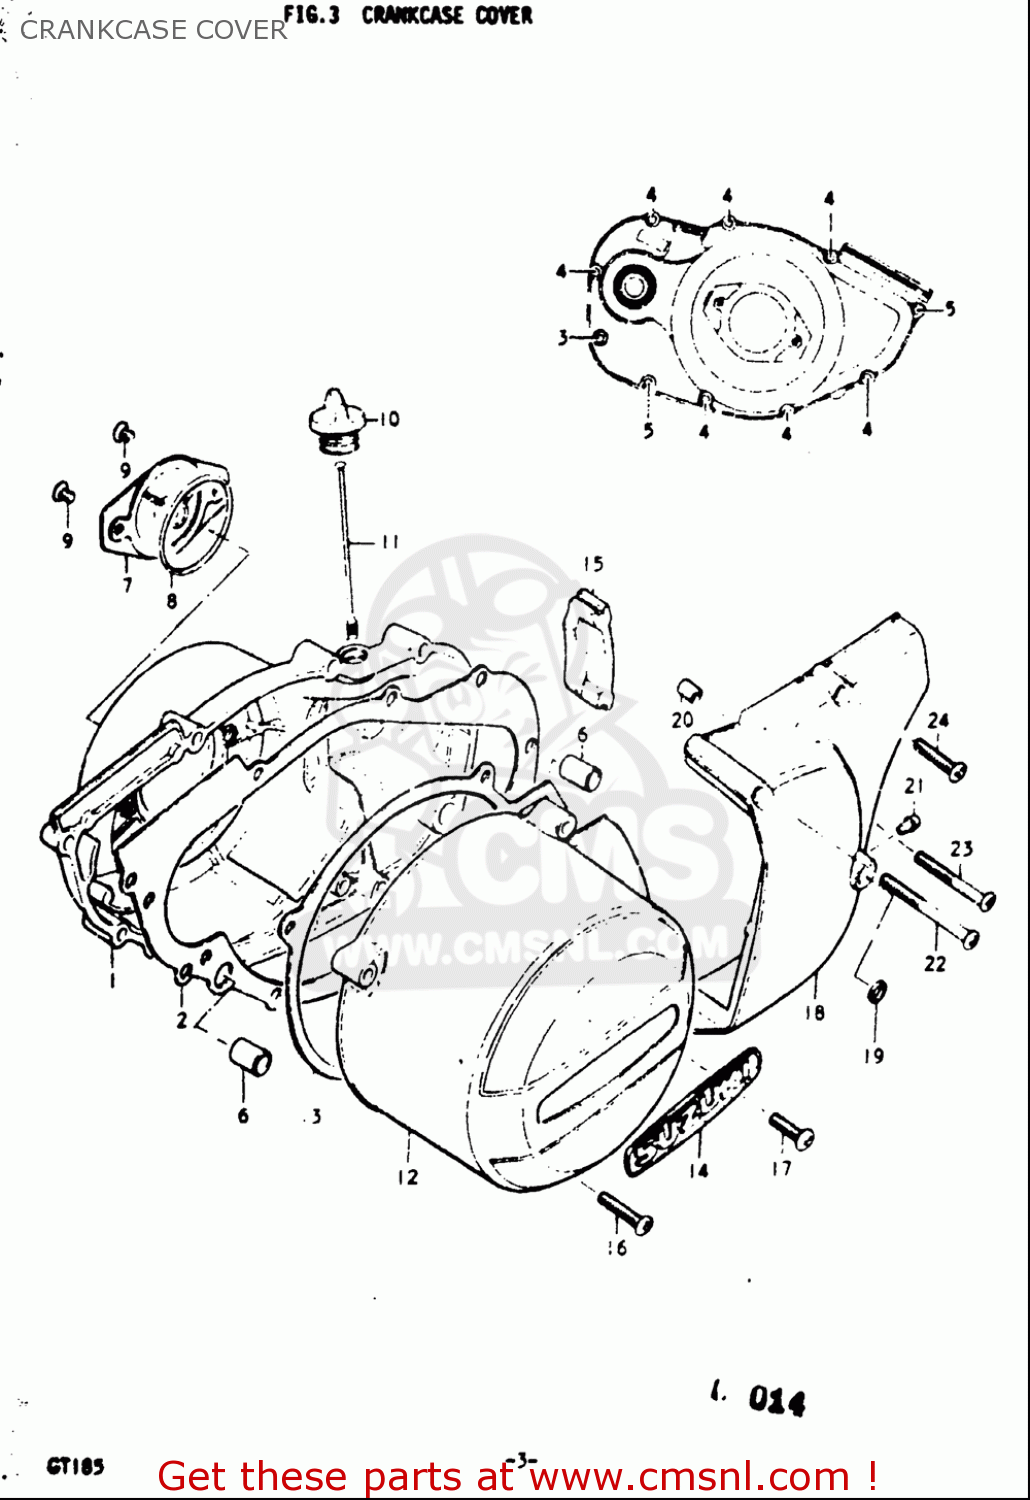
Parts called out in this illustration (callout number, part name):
2	GASKET,CLUTCH COVER (NAS)
3	SCREW
4	SCREW
5	SCREW
6	PIN
8	O RING(D:2.4,ID:57.6)
9	SCREW
10	PLUG
13	GASKET,MAGNETO COVER (NAS)
14	EMBLEM,CONTACT BREAKER CAP
16	SCREW
17	SCREW
19	SEAL,OIL(12X18.5X3)
20	PIN
21	NIPPLE
22	SCREW
23	SCREW
24	SCREW
